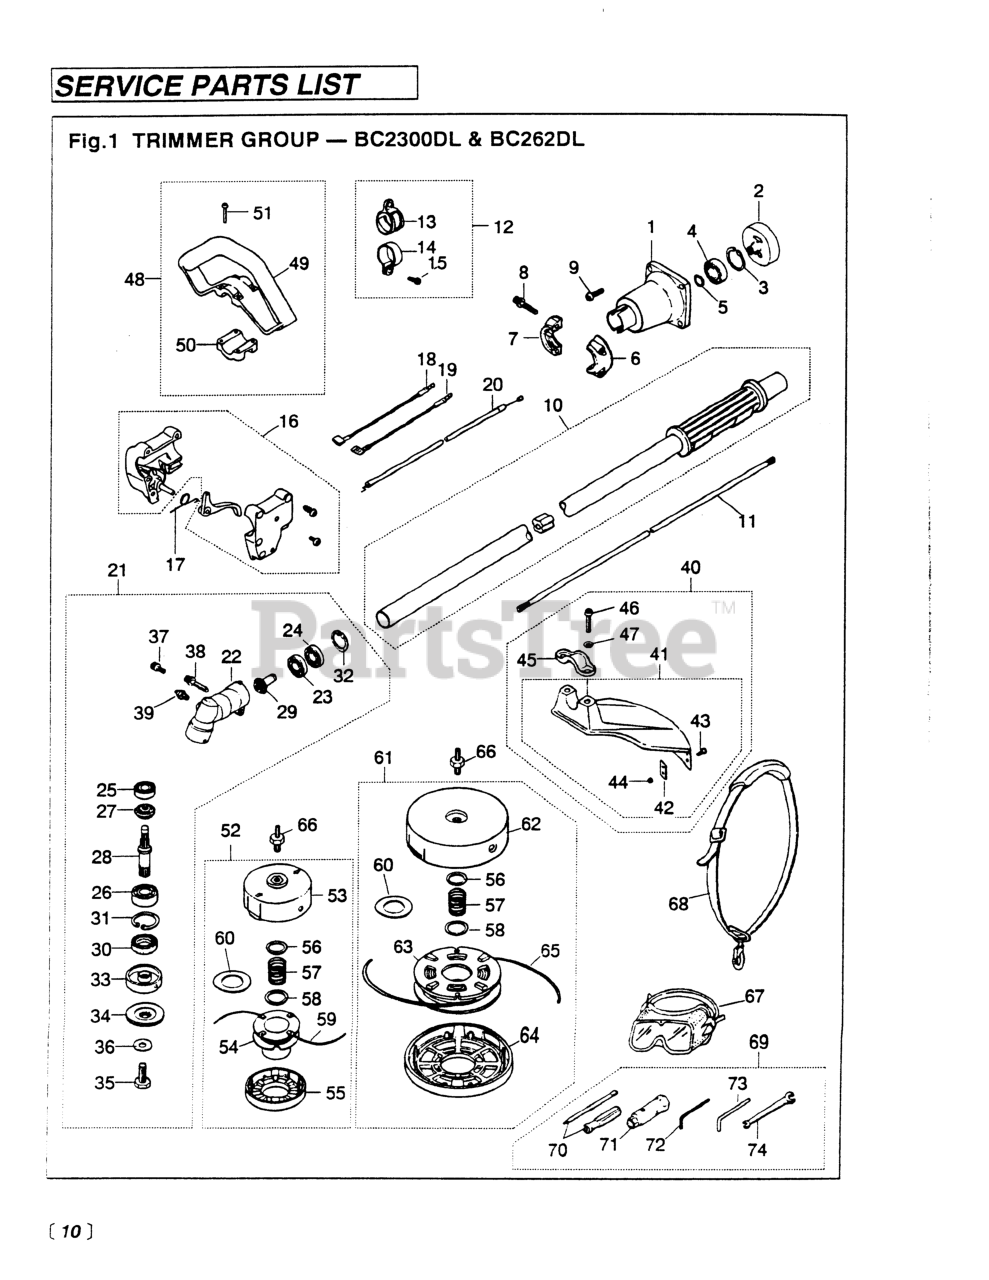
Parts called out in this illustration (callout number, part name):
2	DRUM CLUTCH (USE 6460-12112)
3	RING, SNAP, M28 x 1.2
4	BEARING
6	CLAMP, LEFT
7	CLAMP, RIGHT
8	BOLT
9	BOLT, M6 X 20
12	HANGER COMPLETE
13	HANGER
14	CLAMP
15	SCREW, M5 x 25
17	SPRING, THROTTLE TRIGGER
18	CORD, RED (LEAD WIRE)
19	CORD, BLACK (LEAD WIRE)
21	GEARCASE ASSEMBLY
22	GEARCASE
23	BEARING
24	BEARING
25	BEARING
26	BEARING
27	GEAR
29	PINION
30	SEAL, OIL
31	RING, SNAP
32	RING, SNAP
33	HOLDER (A)
34	HOLDER (B)
36	WASHER
37	BOLT, M5 x 12
38	BOLT, M5 X 25
39	FITTING, GREASE
40	GUARD ASSEMBLY
42	BLADE
43	SCREW, M5 x 12
44	NUT
45	CLAMP
46	BOLT, M6 x 1.30
47	WASHER, M6 X 15
48	HANDLE ASSEMBLY
49	HANDLE
50	CLAMP
51	SCREW, M5 x 30
52	4
56	PLATE, LARGE
58	PLATE, SMALL
59	CORD
60	SPACER
61	6
64	COVER
65	CORD
66	ARBOR, 8MM
67	GOGGLE
68	SHOULDER STRAP ASSY
69	TOOL SET
70	SCREWDRIVER
72	WRENCH (TOOL)
73	BAR
74	SPANNER, 8 X 10 (RPLS 2540- )
